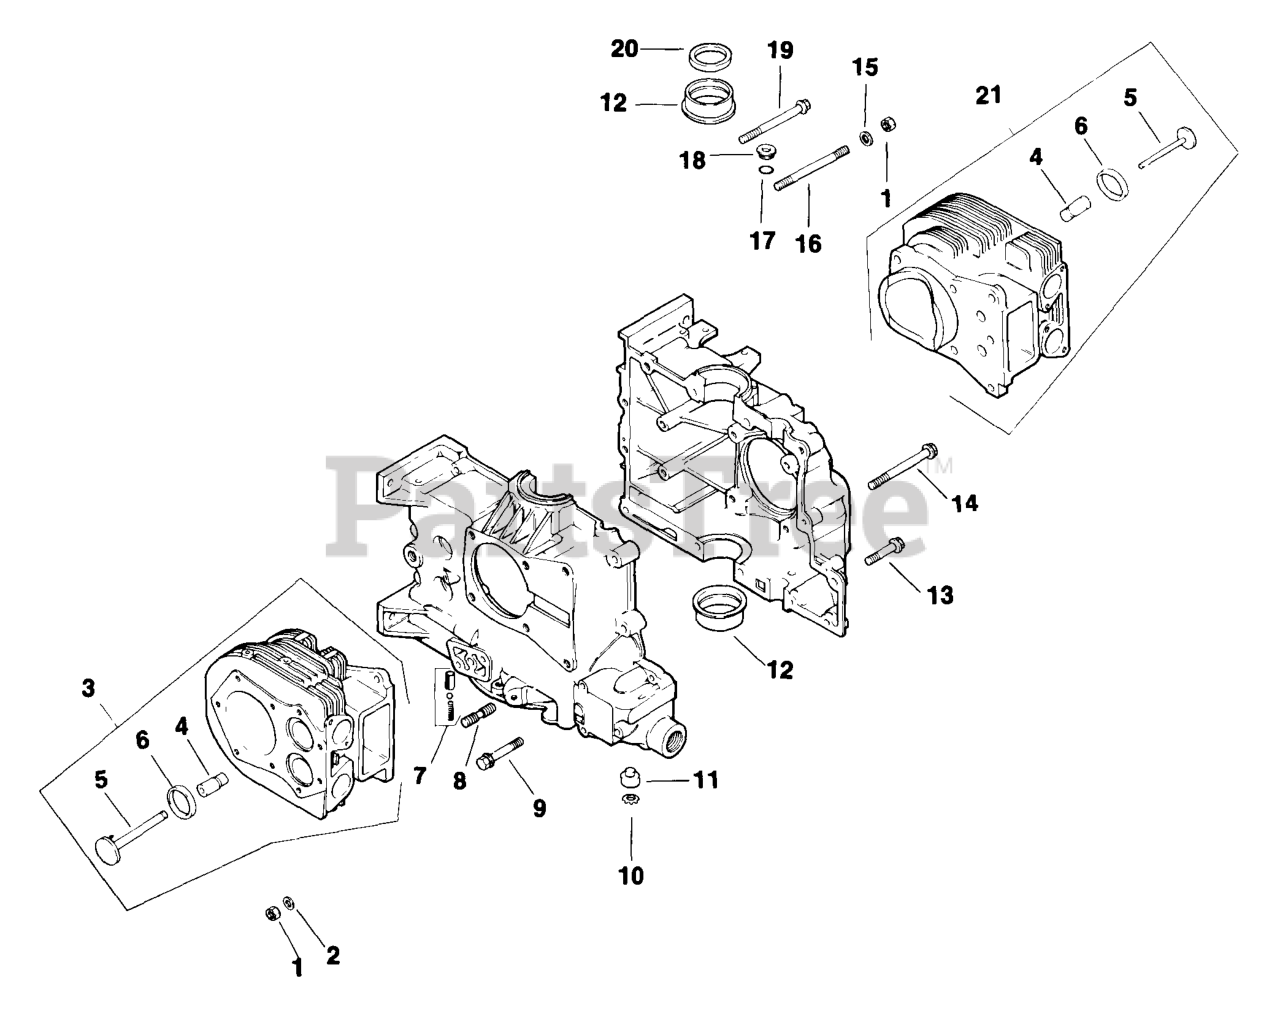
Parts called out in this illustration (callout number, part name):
1	Nut, Hex. 5/16-18
2	Washer, Flat 5/16"
3	Kit, #1 Cylinder Barrel
4	Guide, Valve
5	Valve, Exhaust
6	Insert, Valve Seat
7	Kit, Oil Relief
8	Step Stud 5/16-18x3/4", 3/8-16x5/8", 2" Long
9	Screw, Hex. Flange 5/16-18x2"
10	Ring, Retaining
11	Shaft, Governor
12	Bearing, Sleeve (Std.)
12	Bearing, Sleeve (.010)
12	Bearing, Sleeve (.020)
13	Screw, Hex. Flange 5/16-18x1-1/2"
14	Screw, Hex. Flange 3/8-16x3-5/8"
15	Washer, Plain
16	Stud 5/16-18x4-1/8"
18	Plug 3/4" O.D.
19	Screw, Hex. Flange 5/16-18x3-1/2"
20	Seal, Front Oil
21	Kit, #2 Cylinder Barrel
